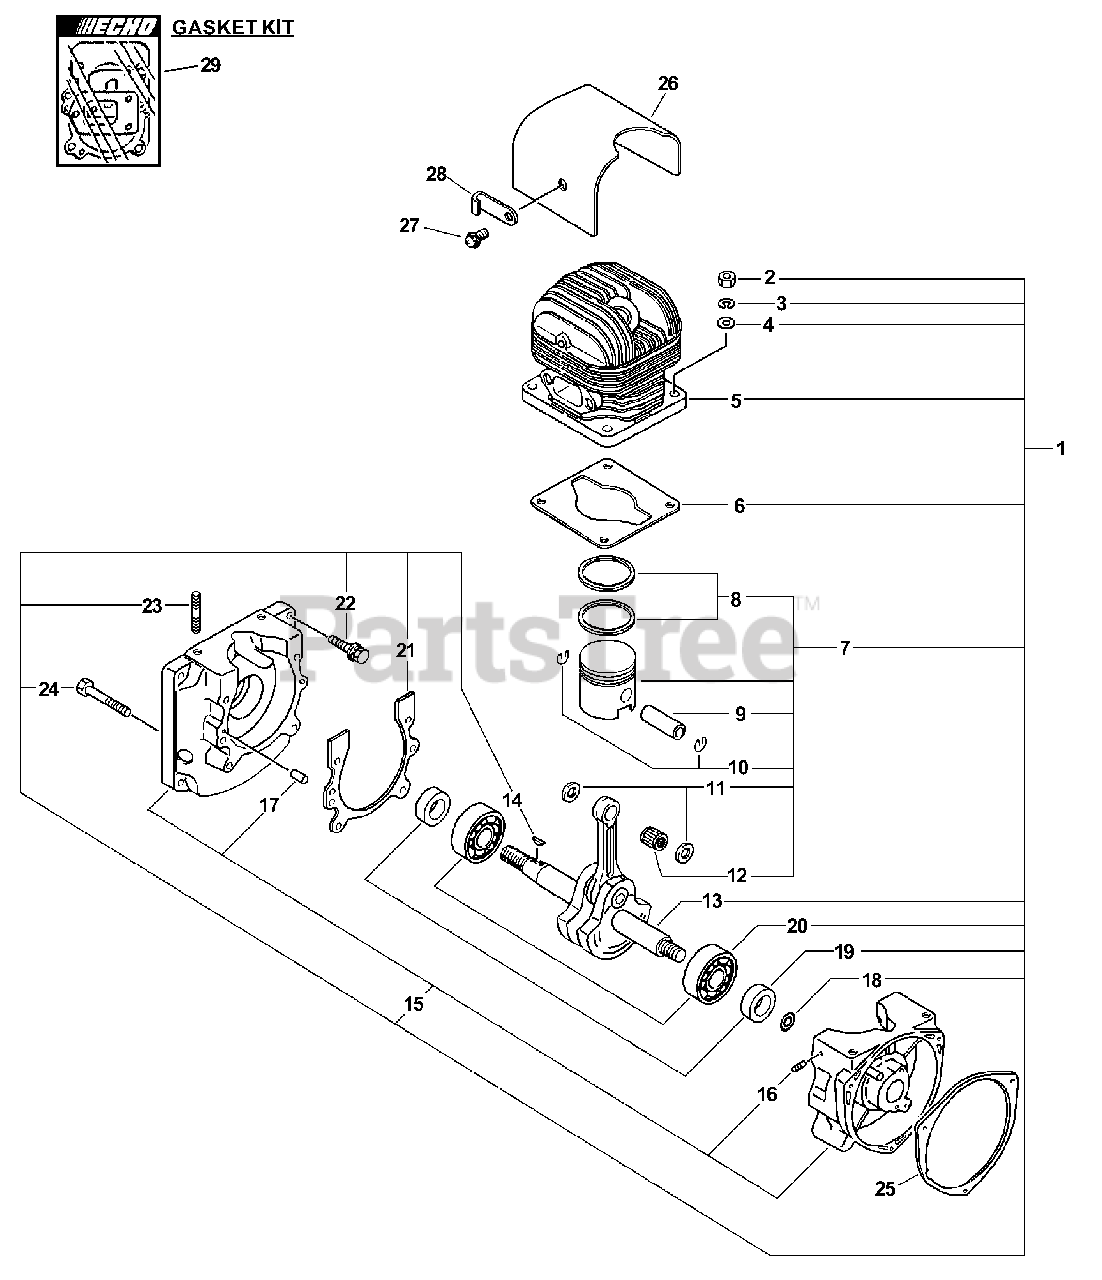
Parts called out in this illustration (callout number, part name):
1	SHORT BLOCK
2	NUT, HEX M6
3	WASHER, SPRING 6
4	WASHER 6.5×11.5×0.8
5	CYLINDER
6	GASKET, CYLINDER
7	PISTON KIT
8	RING, PISTON
9	PIN, PISTON
10	RING, SNAP 8
11	WASHER, THRUST
12	BEARING, NEEDLE 10
13	CRANKSHAFT ASSY
15	CRANKCASE KIT
16	CONNECTOR
17	PIN, LOCATING 5×10
18	WASHER PB-400
19	SEAL, OIL
20	BEARING, BALL
21	GASKET
25	GASKET, STARTER
26	COVER, CYLINDER
27	BOLT 6×10
28	CLIP, CORD
29	GASKET KIT
